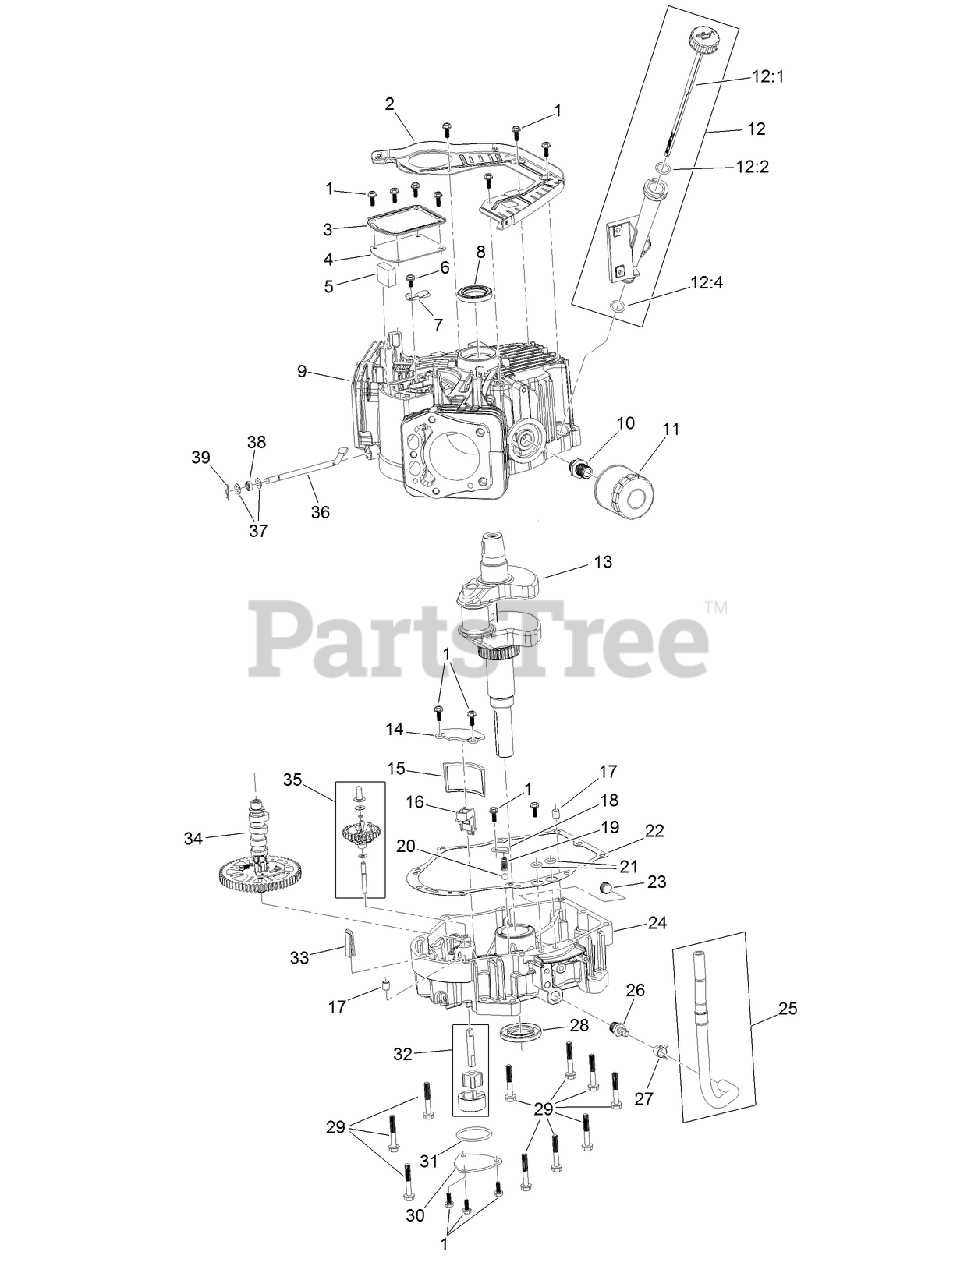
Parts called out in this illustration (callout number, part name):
1	SCREW-HHF
2	BAFFLE
3	COVER-BREATHER
4	GASKET-BREATHER
5	FILTER-BREATHER
6	SCREW-HHF
7	VALVE-BREATHER
8	SEAL-OIL
9	CRANKCASE
10	FITTING-THREADED, OIL FILTER
11	FILTER-OIL
12	OIL TUBE ASM
12:1	DIPSTICK
12:2	O-RING
12:4	O-RING
13	CRANKSHAFT
14	COVER-SCREEN, OIL
15	SCREEN-OIL
16	RETAINER-SCREEN
17	PIN-DOWEL
18	PLATE-RETAINER
19	SPRING
20	VALVE-BALL
21	O-RING
22	GASKET-COVER, CRANKCASE
23	PLUG-DRAIN
24	COVER-CRANKCASE
25	OIL DRAIN HOSE ASM
26	FITTING-HOSE
27	CLAMP-HOSE
29	SCREW-HHF
30	COVER-OIL PUMP
31	O-RING
32	OIL PUMP ASM
33	DEFLECTOR-OIL, RUBBER
34	CAMSHAFT
35	GOVERNOR ASM
36	SHAFT-GOVERNOR
37	WASHER-PLAIN
38	SEAL-OIL
39	PIN-HAIR
